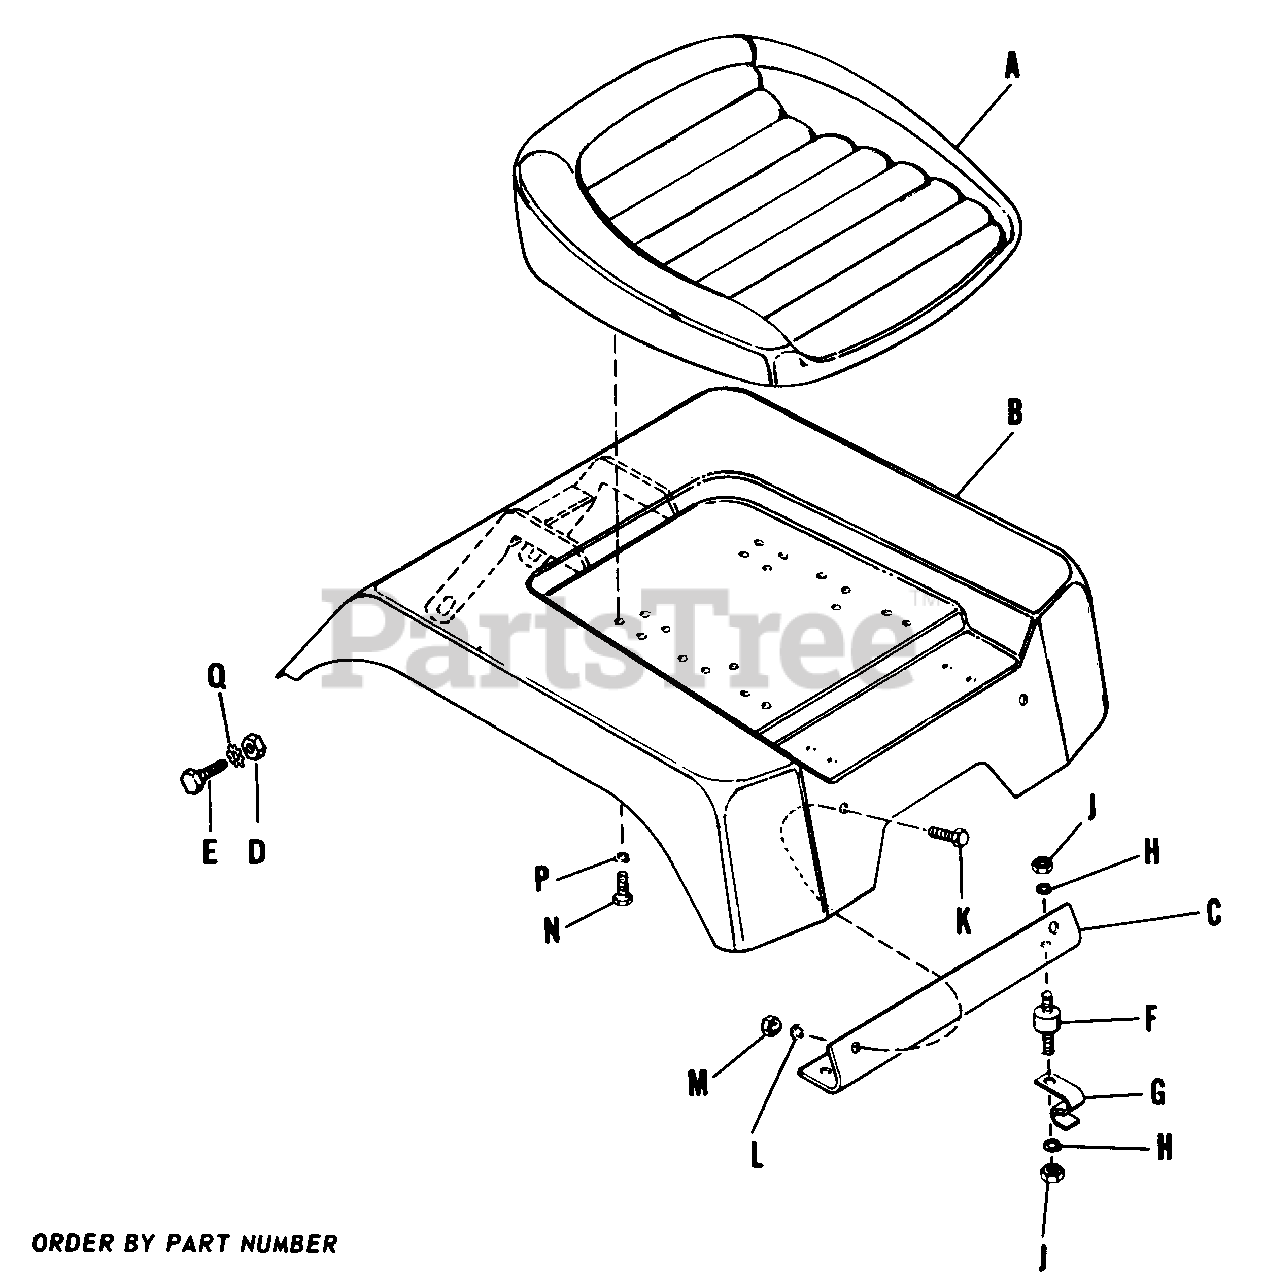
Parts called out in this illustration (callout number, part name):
A	Seat Assembly
B	Seat Deck Assembly
C	Seat Deck Bracket, Front
D	Hex. Locknut, Full, 3/8"-16
E	Hex Head Capscrew, 3/8"-16 x 1-1/4"
F	Cushion Connector, Front
G	Spring Clip
H	Lock Washer, 5/16"
J	Hex. Nut, Full, 5/16"-18
K	Hex. Head Capscrew, 5/16" 18 x 5/8" lg.
L	Lockwasher, 5/16"
M	Hex. Nut, Full, 5/16"-18
N	Hex. Head Capscrew, 5/16"-18 x 5/8" lg.
P	Lockwasher, 5/16"
Q	Lockwasher
